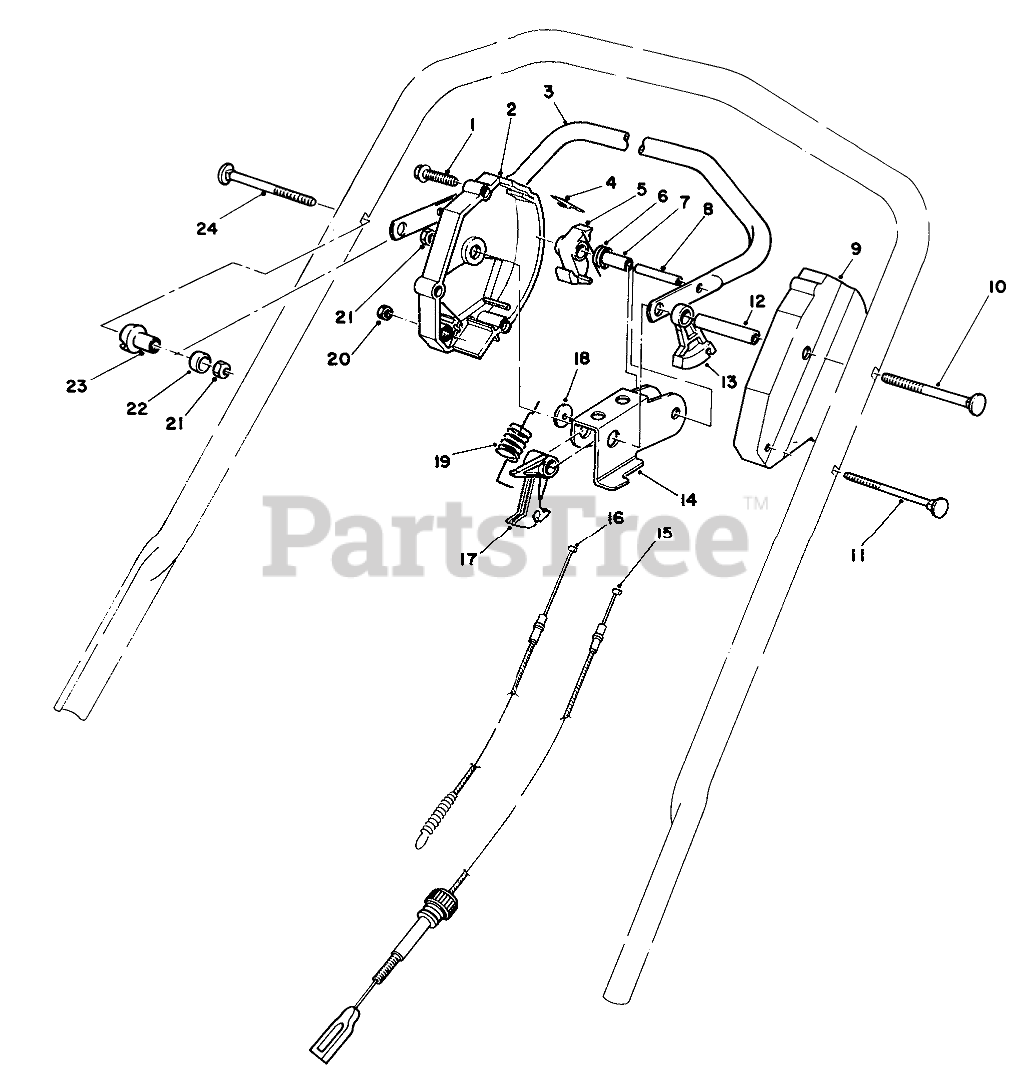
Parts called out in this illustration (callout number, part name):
1	SCREW-HWHTF
2	Housing Control R.H.
3	Bar-Control
4	SPRING-LEAF
5	HOOK-CONTROL
6	SPRING-TORSION
7	SPACER
8	PIN-ROLL, SLOTTED
9	HOUSING-CONTROL, LH
10	5/16-18 X 3 HNDLE SCREW
11	HANDLE SCREW
12	TUBING-SPACER
13	LEVER-TRACTION
14	Rocker
15	TRACTION CABLE
16	Cable-Clutch
17	LEVER-CABLE
18	PLASTIC WASHER
19	Spring-Detent
20	NUT-LOCK, NI
21	NUT-LOCK, NI
22	SPACER-NYLON
23	SPACER-SUPPORT
24	5/16-18 X 2 HNDLE SCREW
